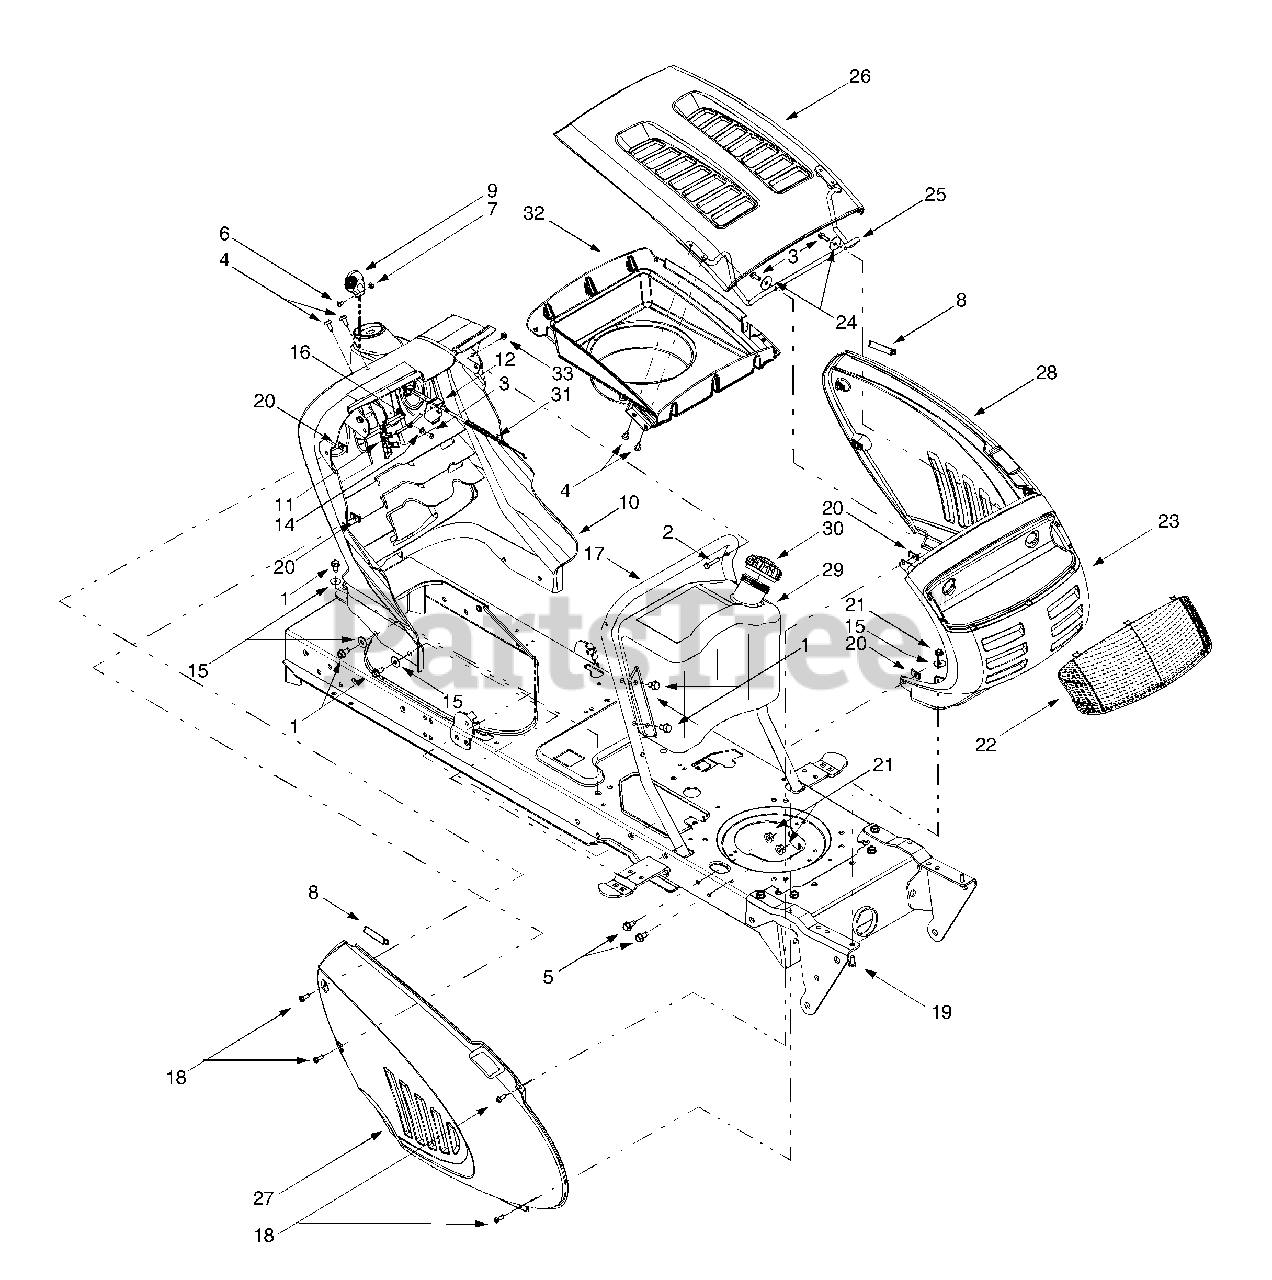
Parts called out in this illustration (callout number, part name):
1	Self-tapping Screw, 5/16-18 x .625
2	Self-tapping Screw, 1/4-20 x 1.0
3	Self-tapping Screw, 1/4-15 x .75
4	Torx Self-tapping Screw, 5/16-18 x .625
5	Screw, 5/16-18 x .875
6	Torx Screw, #8-32 x .375
7	Hex Nut, 8-32
8	Five-inch Trim Strip
9	Throttle Control Lever
10	Dash Panel
11	Plastic Plug
12	Parking Brake Button
14	Flat Washer, .281 x .5 x .063
15	Flat Washer, .349 x 1.0 x .063
16	Pivot Rod
19	Hex Cap Screw, 5/16-18 x .75
20	U-type Speed Nut, 1/4-20
21	Flange Lock Nut, 5/16-18
22	Lens, 9-style
23	Grille, 9-style
24	Flat Washer, .285 x 1.25 x .08
25	Hood Hinge Rod
30	Fuel Cap
31	Choke Knob/Cable Assembly
32	Hood Plenum
33	Hex Flange Lock Nut, 1/4-20
